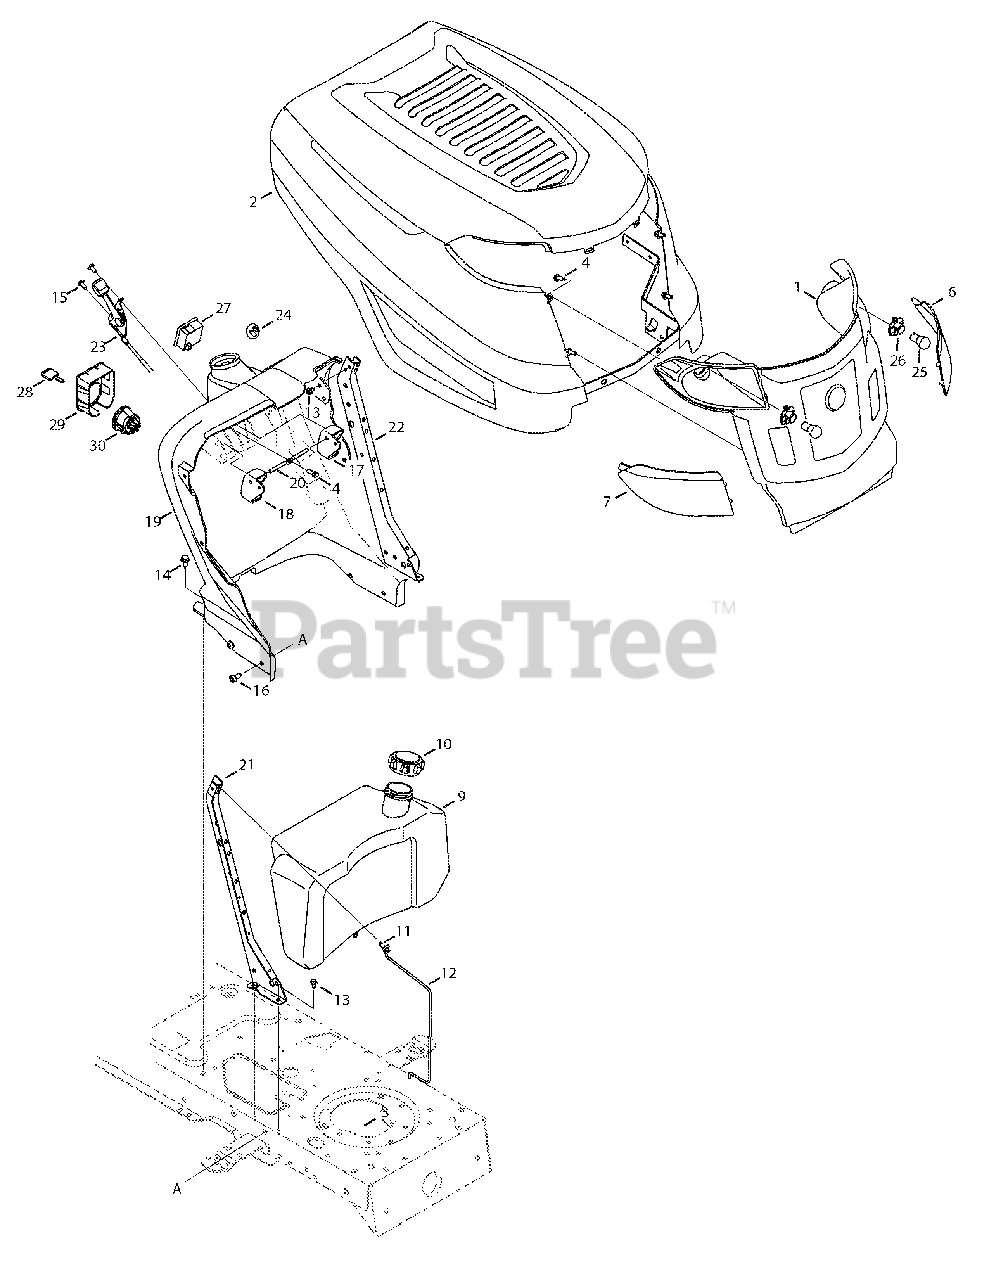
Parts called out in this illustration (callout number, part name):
1	Grill Assembly
3	Screw, 5/16-18, 0.625
4	Self-tapping Screw, 1/4-15 x.75
5	Cable Tie, 3/16 x .05 x 7.4
6	Headlight Lens
7	Headlight Lens
8	Shoulder Screw,.43 x.29
9	Fuel Tank, 2.5 gal.
10	Fuel Tank Cap
11	Screw, 1/4-20, 0.750
12	Gas Tank Support Rod
13	Screw, 1/4-20, 0.500
14	Screw, 5/16-18 x 0.500
15	Screw, 1/4-14 x.625
16	Screw, 5/16-18 x.75
17	Parking Brake Button
18	Cruise Control Button
19	Dash Panel w/ Manual PTO
20	Brake/Cruise Pivot Rod
23	Throttle/Choke Control Cable
24	Choke Plug
25	Headlamp, 12V
26	Lamp Socket
27	Systems Ind. Monitor w/ Amtr.
28	Ignition Key w/ plastic cover
28	Ignition Key w/o plastic cover
29	Switch Housing
30	Module, Ignition Switch
